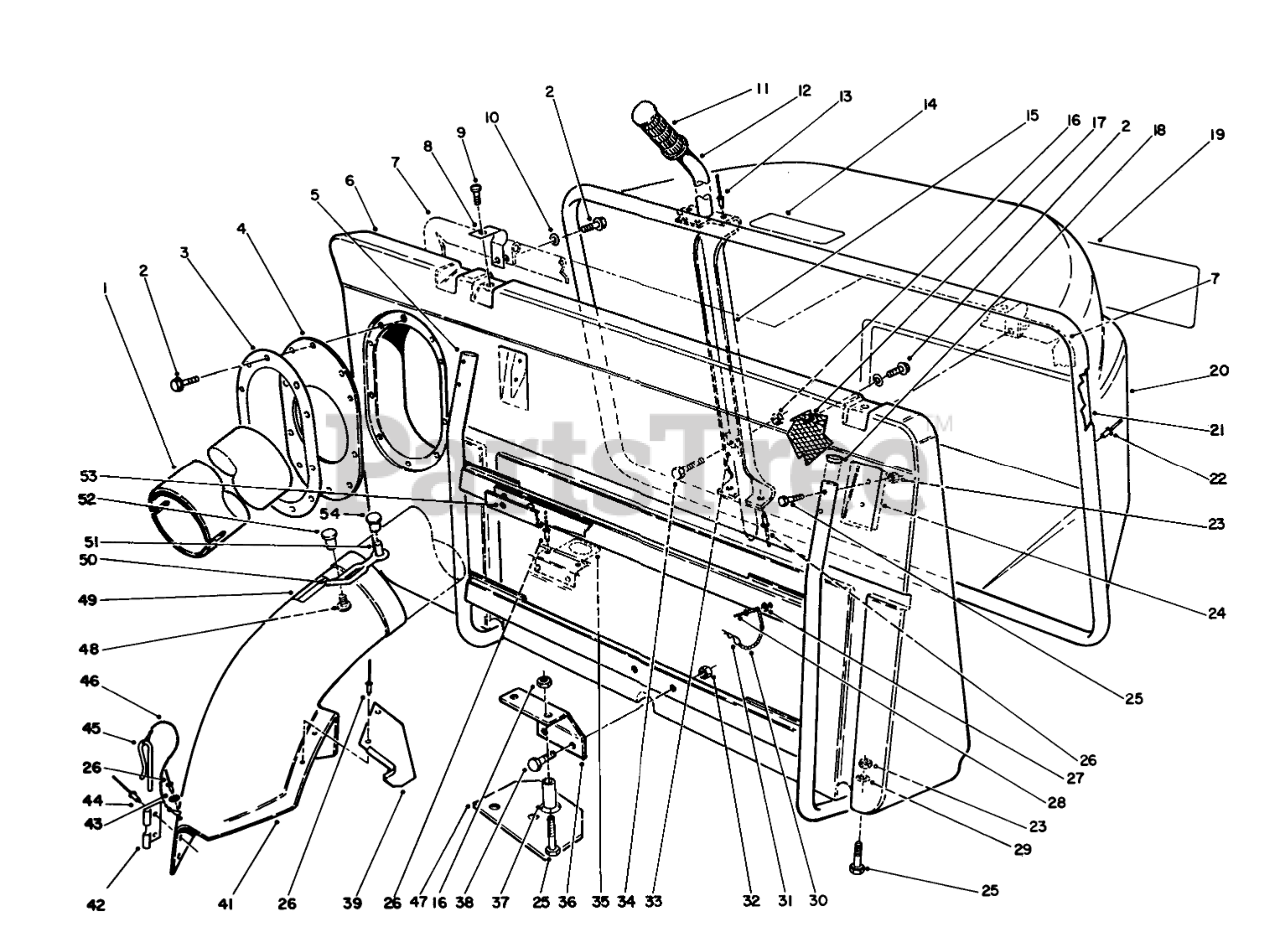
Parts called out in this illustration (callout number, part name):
1	GRASS DISCHARGE TUBE
2	SCREW-HWHTF
3	RING-RETAINING
4	RING-RETAINER, RUBBER
5	Frame
6	BAG-FRONT
7	SEAL-BAG
8	Bracket-Hinge
9	SCREW-HSBH
10	WASHER-FLAT
11	GRIP-HANDLE
12	HANDLE-DUMP
13	NUT-LOCK
14	Decal Warning
15	Channel-Dump Handle
16	NUT-LOCK, NI
17	Screen Bag
19	DECAL - TORO
20	BASKET-GRASS
21	Frame-Grass Basket
22	NUT-LOCK
23	NUT-LOCK, NI
24	Plate-Backup
25	SCREW-HH
26	RIVET-BLIND
27	WASHER
29	WASHER-FLAT
30	10 LINK CHAIN W/O HOOK
31	PIN-HAIR
32	NUT-LOCK, NI
33	GUIDE-HANDLE, DUMP
34	SCREW-HH
35	Latch
36	Bracket-Hitch
37	Spacer
38	SCREW-HH
39	CHUTE SUPT BRKT
41	Chute Assembly (Incl. Ref. #26, 39, 42-46, 54 & 55)
42	BRACKET-MOUNTING, CHUTE
43	WASHER-PLAIN
44	RIVET-BLIND
45	PIN-LOCKING, CHUTE
46	LANYARD
47	Plate-Hitch
48	Screw
49	DECAL-DANGER
50	RETAINER-DUCT
51	SPACER-INTERLOCK
53	Adapter-Bagger (Incl. Ref. #27, 28, 30 & 31)
54	FASTENER-PANEL
